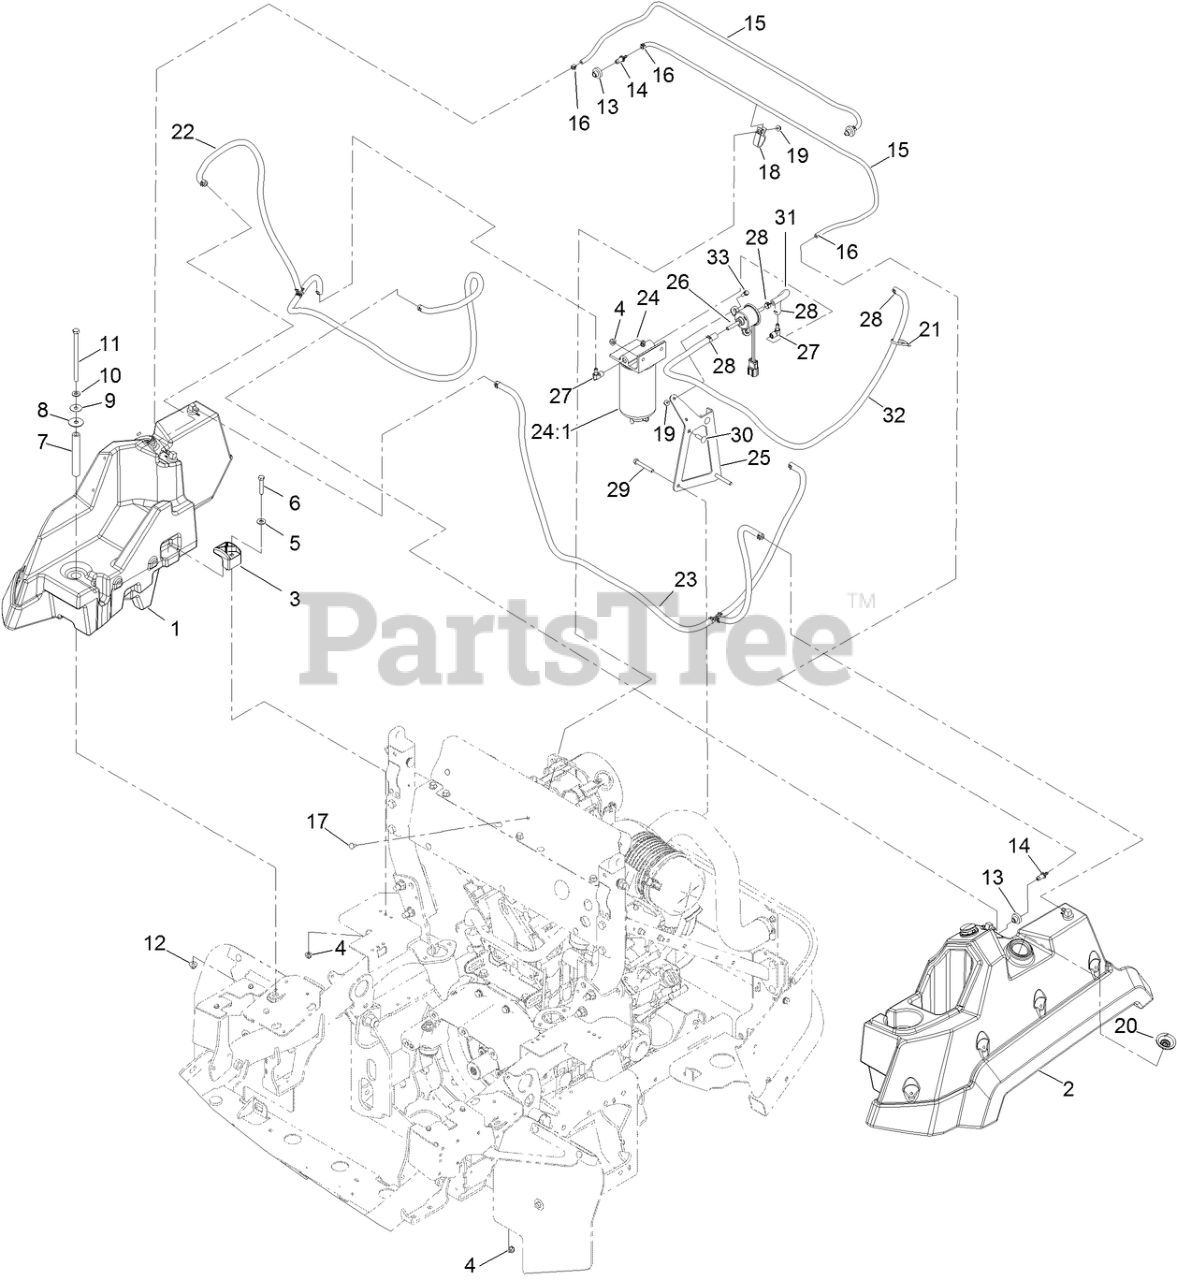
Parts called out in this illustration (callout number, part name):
1	RH FUEL TANK ASM
2	LH FUEL TANK ASM
4	NUT-HF, NI
5	WASHER-FLAT
6	SCREW-HH
7	TUBE-SPACER
8	WASHER-RUBBER
9	WASHER-PLAIN
10	WASHER-FLAT
11	SCREW-HH
12	NUT-HF, NI
13	BUSHING
14	FITTING-ORIFICE, STRAIGHT
15	HOSE-VENT, TANK
16	CLAMP-HOSE
17	SCREW-CARR
18	CLAMP-HOSE
19	NUT-HF
20	CAP-FUEL, DIESEL
21	TIE-CABLE
22	FUEL SUCTION LINE ASM
23	FUEL RETURN LINE ASM
24	SEPARATOR FILTER ASM
24:1	FILTER-FUEL/WATER SEPARATOR
25	BRACKET-FILTER, FUEL
26	PUMP-FUEL, ELECTRIC
27	FITTING-HYD, 90
28	CLAMP-HOSE
29	SCREW-HH
30	SCREW-CARR
31	HOSE-FUEL
32	HOSE-FUEL
33	SCREW-HWH
